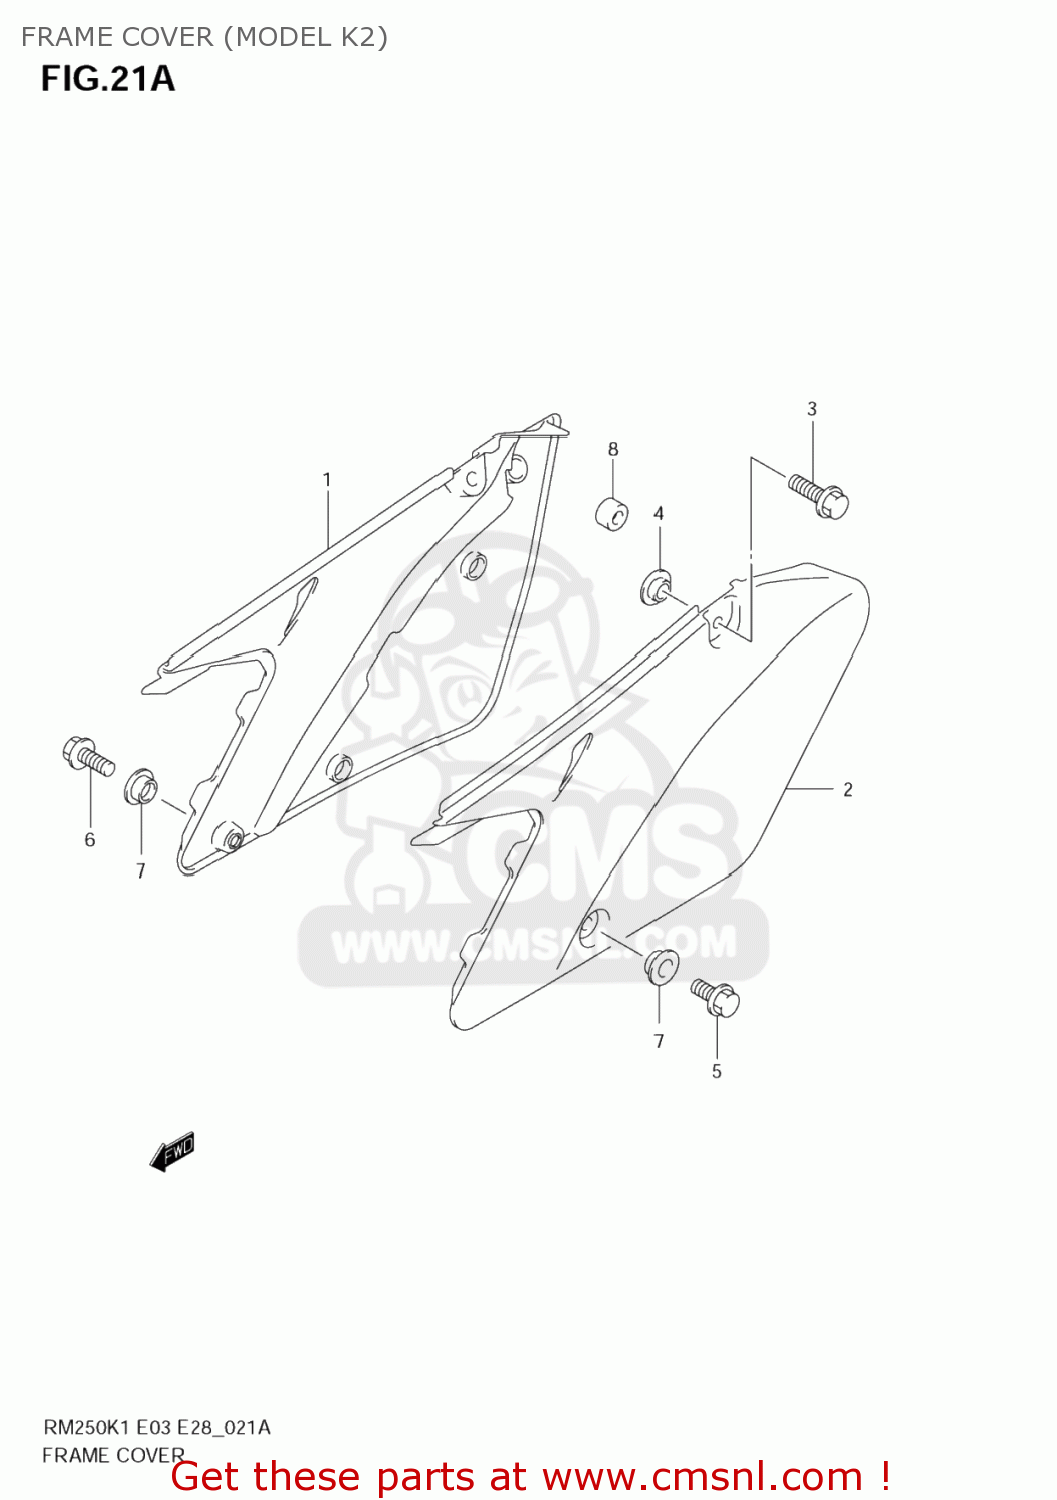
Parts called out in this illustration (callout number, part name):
1	COVER,FRAME,R(YELLOW)
2	COVER,FRAME,L(YELLOW)
3	BOLT
4	WASHER,FRAME C
5	BOLT(6X12)
6	BOLT(6X16)
7	WASHER
8	CUSHION,FRAME COVER,R
